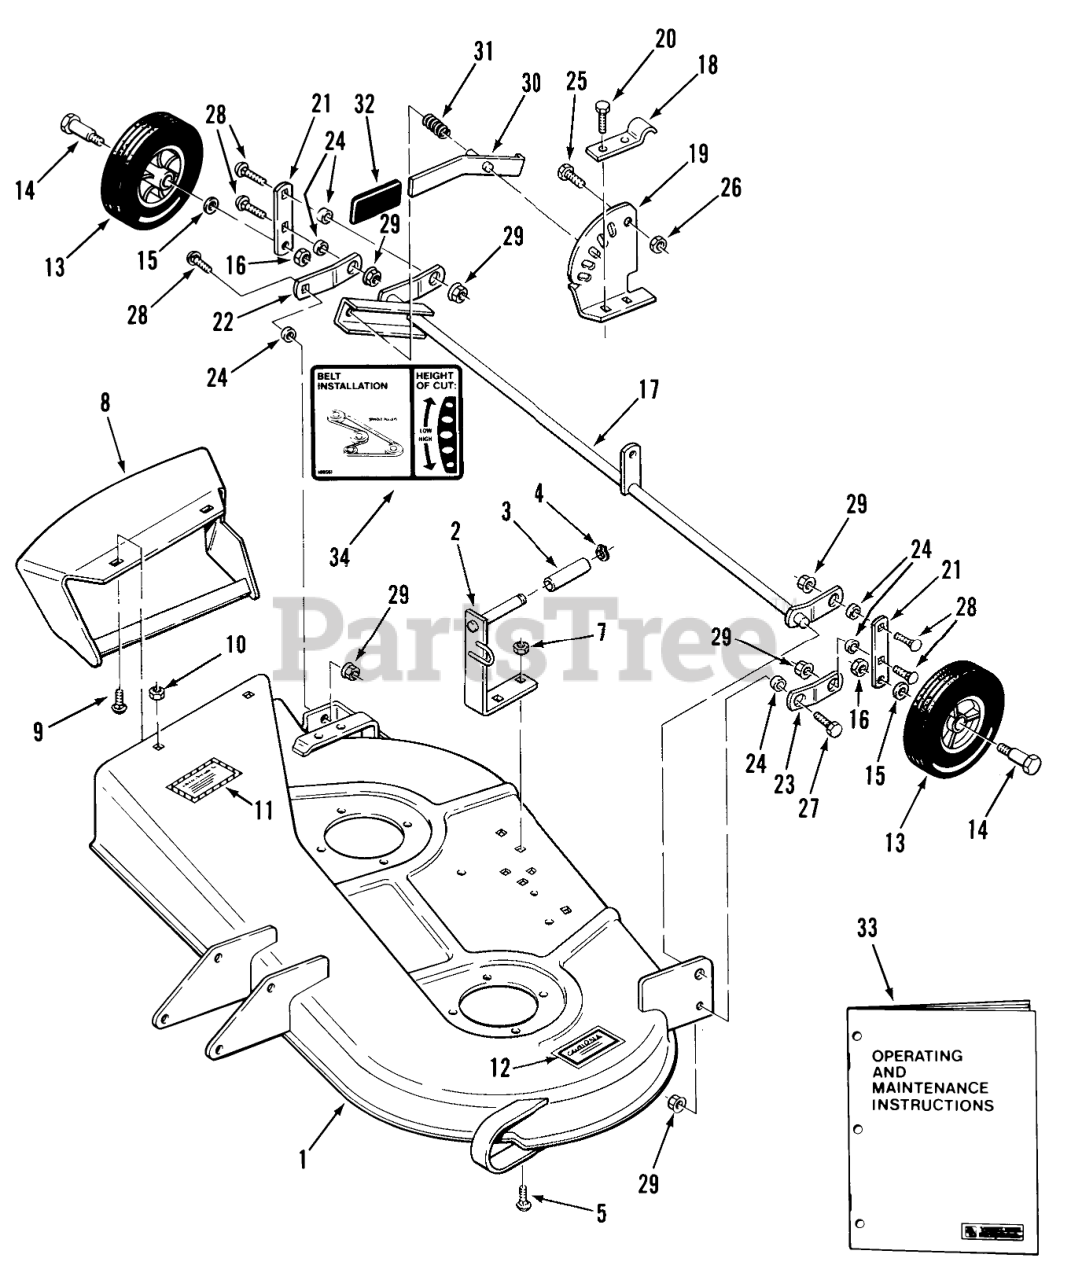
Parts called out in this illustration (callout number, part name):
1	Mower Deck
1	Spindle Assembly (Includes Items 2 Thru 8)
2	ASSY-BRACKET GUID R
3	SPACER
4	Snap Ring
5	Bolt-Carriage
7	Nut
8	ASSY-CHUTE EXT R
9	CARRIAGE BOLT -4
10	Nut
11	DECAL
12	Caution Decal
13	WHEEL-GAUGE
15	WASHER
16	Nut
17	Gage Wheel Support
18	Pivot Bracket
19	Quadrant
20	Bolt
21	LINK R
22	ARM-PIVOT RH R
23	Arm LH
24	SPACER
26	Nut
27	BOLT
28	Bolt
29	LOCKNUT-FLANGE
30	Lever
31	SPRING-COMPRESSION
33	Owner-s Manual-Mower
34	DECAL-BELT&HEIGHT
